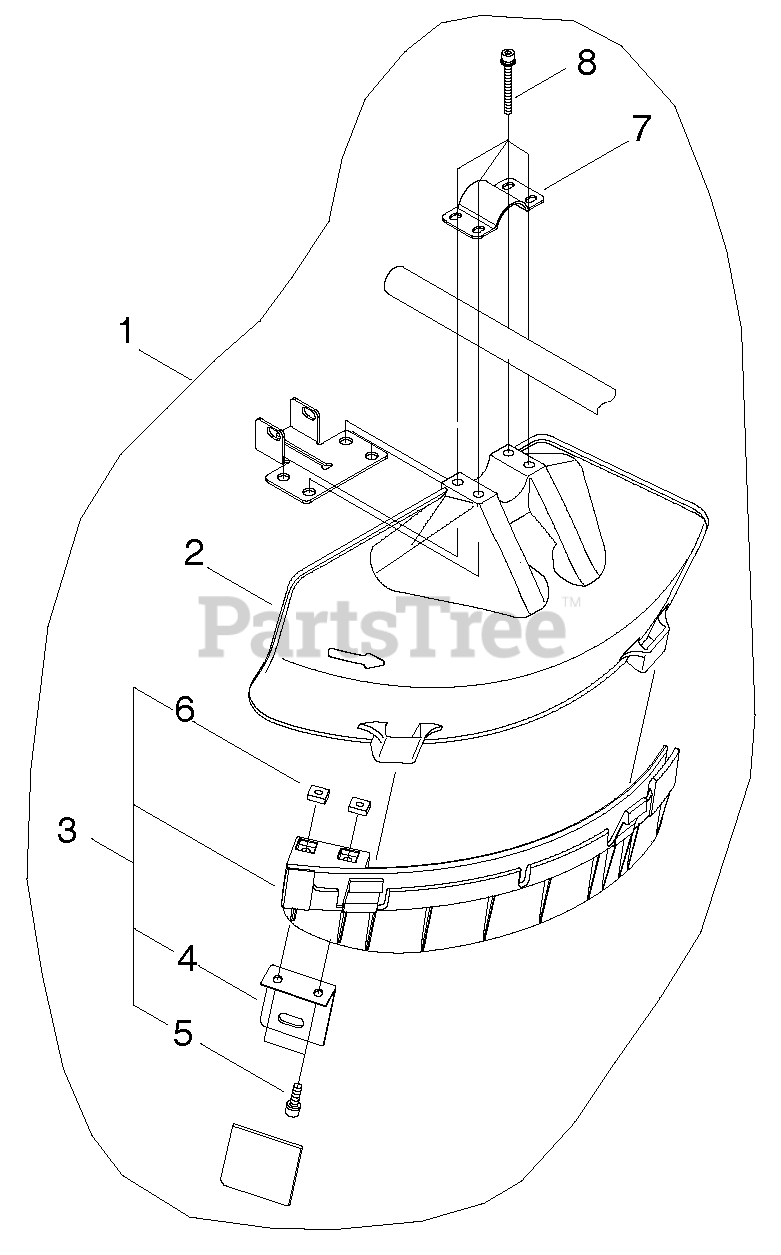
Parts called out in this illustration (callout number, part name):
1	DEBRIS SHIELD KIT
2	SHIELD, DEBRIS
3	SHIELD GUARD KIT
4	KNIFE, TRIMMER LINE
5	SCREW - 5X16
6	NUT - 5
7	CLAMP - UPPER
8	SCREW - 5X45
